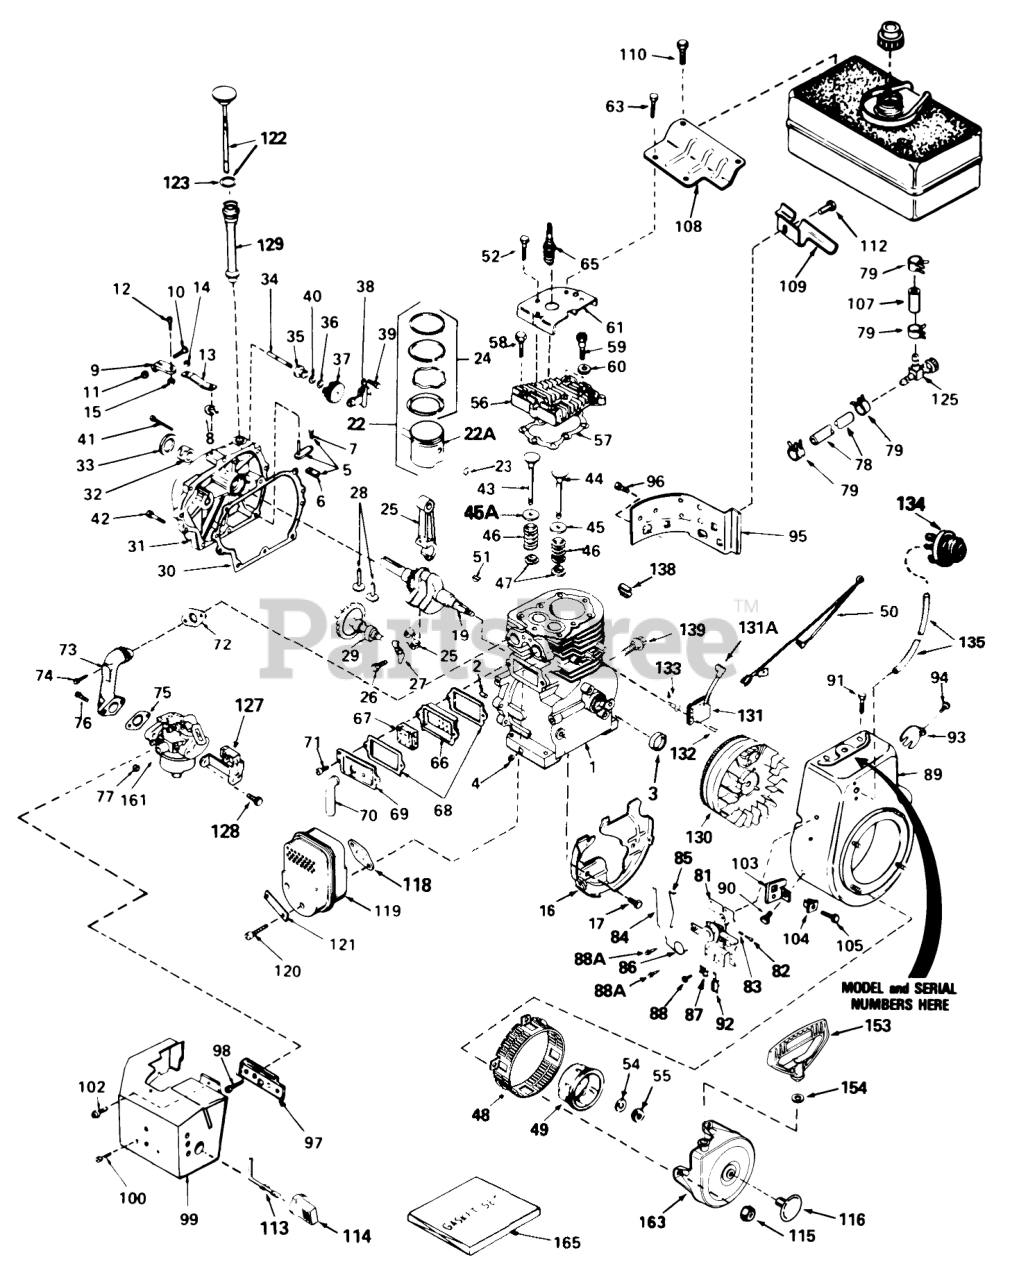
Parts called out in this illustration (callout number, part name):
1	Cylinder Assy. (Incl. Ref. #2, 3 & 4)
2	Pin-Dowel
3	Seal-Oil
4	Plug-Drain, Oil (SQH 1/4-18)
5	Rod Assembly-Governor (Incl. Ref. #6 & 7)
6	Yoke-Governor
7	Screw (6-40x5/16)
8	Ring-Retaining
9	Clamp-Lever, Governor
11	Nut-Lock
12	Screw
13	Lever-Governor
14	Washer-Lock
15	Nut-Lock
16	Baffle-Blower Housing
17	Screw (1/4-20x19/32)
19	Crankshaft
22	Piston-Pin & Ring Assy. (Std.) (Incl. Ref. #22A, 23 & 24)
22	Piston-Pin & Ring Assy. (.010 oversize) (Incl. Ref. #22A, 23 & 24)
22	Piston-Pin & Ring Assy. (.020 oversize) (Incl. Ref. #22A, 23 & 24)
22A	Piston & Pin Assy. (Std.) (Incl. Ref. #23)
22A	Piston & Pin Assy. (.010 oversize) (Incl. Ref. #23)
22A	Piston & Pin Assy. (.020 oversize) (Incl. Ref. #23)
23	Ring-Retaining, Piston Pin
24	Ring Set (Std.)
24	Ring Set (.010" OS)
24	Ring Set (.020" OS)
25	Rod Assy.Connecting (Incl. Ref. #26 & 27)
26	Bolt-Rod
27	Dipper-Oil
28	Lifter-Valve
29	Camshaft (MCR)
30	Cylinder Cover Gasket
31	Cover-Cylinder (Incl. Ref. #32, 33 & 34)
32	Bushing-Crankshaft
33	Seal-Oil
34	Shaft-Governor
35	Spool-Governor
36	Ring-Retaining
37	Gear Assy.-Governor (Incl. Ref. #40)
38	Bracket-Gear, Governor
39	Screw (10-24x1/2)
40	Washer-Flat
41	Screw (1/4-20x1-3/16)
42	Screw (1/4-20x1-11/16)
43	Valve-Intake (Std.) (Incl. Ref. #47)
43	Valve-Intake (1/32"oversize) (Incl. Ref. #47)
44	Valve-Exhaust (Std.) (Incl. Ref. #47)
44	Valve-Exhaust (1/32"oversize) (Incl. Ref. #47)
45	Cap-Spring, Valve
45A	Seal-Intake Valve
46	Spring-Valve
47	Keeper-Spring, Valve
48	Screen-Starter
49	Cup-Starter
50	Ground Wire
51	Key-Flywheel
52	Screw (1/4-20 X 5/8)
54	Washer-Belleville
55	Nut-Flywheel
56	Head Cylinder
57	Gasket-Cylinder Head
58	Screw (5/16-18x1-1/2)
59	Screw (5/16-18x1-25/32)
60	Washer-Flat
61	Cover-Cylinder Head
63	Screw
65	Spark Plug-Resistor (R J19 L M)
66	Body-Breather
67	Element-Breather
68	Gasket-Breather
69	Cover-Valve
70	Tube-Breather
72	Gasket-Intake
73	Pipe-Intake
74	Screw (T-30, 5/16-18x1-3/32)
75	Gasket-Carburetor To Intake Pipe
76	Screw (1/4-28x1)
77	Nut and Lock Washer (1/4-28)
78	Line-Fuel
79	Clamp-Line, Fuel
81	Control Assy. Speed (Incl. Ref. #82, 83, 86 & 92)
82	Screw
83	Spring-Compression
84	Link-Governor
85	Link-Throttle
86	Spring-Throttle
87	Conduit
88	Screw (10-32 x 3/8)
88A	Screw (10-32 x 1/2)
89	Housing-Blower
91	Screw (5/16-18x3/4)
92	Terminal
94	Screw (8-32 x 3/8)
95	Extension-Housing, Blower
97	Bracket-Carburetor
98	Screw (8-32x27/64)
99	Cover-Carburetor
100	Screw (10-32 x 3/8)
102	Screw (10-32x1/2)
103	Bracket
104	Grommet
105	Screw
107	Line-Fuel (8.62)
108	Bracket-Tank, Fuel (Black)
109	Bracket-Tank, Fuel
110	Screw (1/4-15x7/8)
112	Screw (1/4-20x19/32)
113	Rod-Choke
114	Knob-Control
115	Nut and Lock Washer (1/4-28)
116	Plug Starter
118	Gasket Exhaust
119	Muffler
120	Screw
121	Plate-Locking
122	Dipstick-Oil (Incl. Ref. #123)
125	Valve-Shut Off
127	Bracket-Choke
128	Screw (10-32 x 1/2)
129	Tube Fill
130	Flywheel (W/Ring Gear)
131	Solid State Assembly (Incl. Ref. #131A)
131A	Cover-Spark Plug
132	Screw
133	Stud
134	Primer Assy.
135	Line-Primer
138	Clip-Wire
139	Screw (1/4-20x1/2)
153	Handle-Starter, Mitten Grip
161	Carburetor (Incl. Ref. #75)
163	Starter-Rewind
165	Gasket Set
